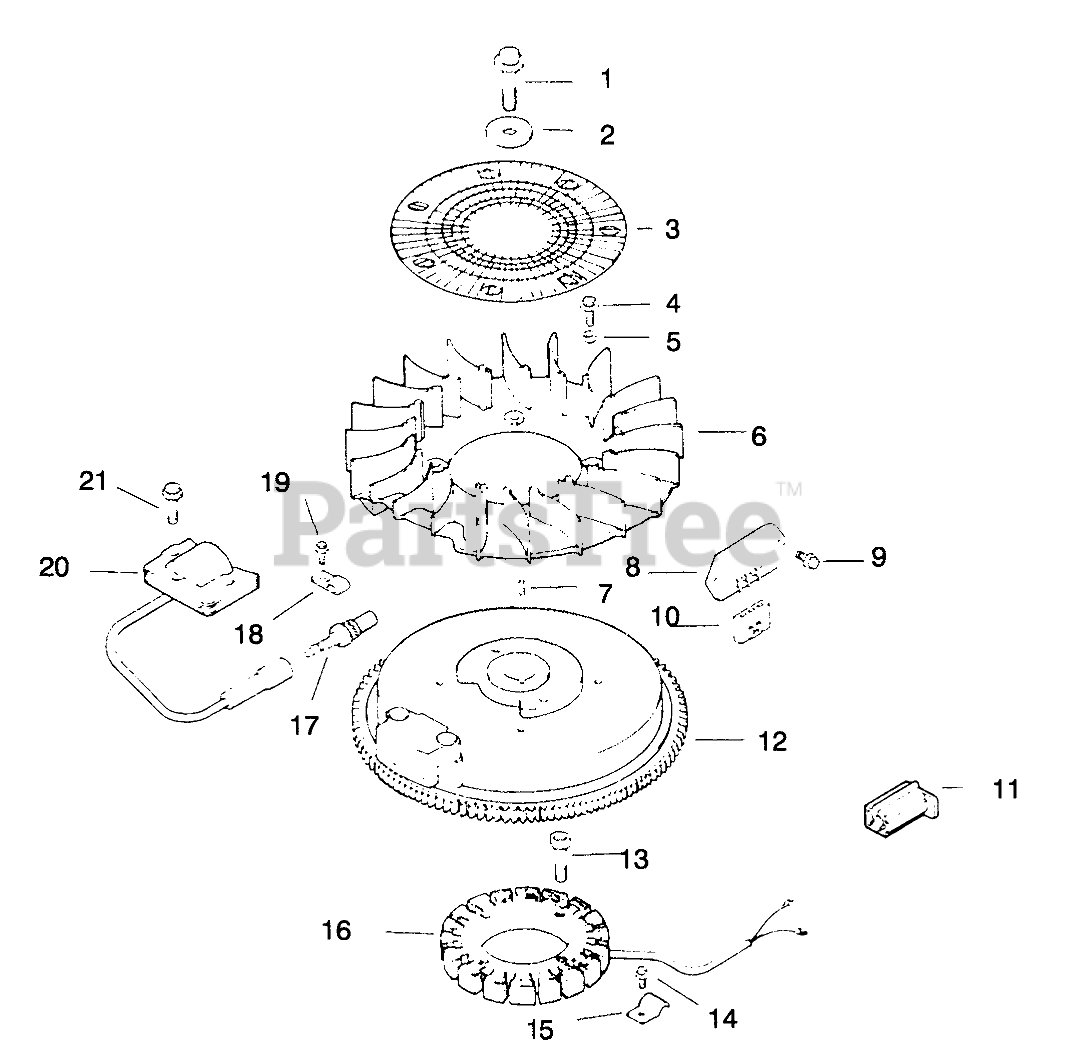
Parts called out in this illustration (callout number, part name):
1	Screw
2	Washer-Flat
3	Screen-Grass
4	Screw
5	Spacer
6	Fan
7	Key
8	Rectifier-Unregulated
9	Screw
10	Connector
11	Connector
12	Flywheel ASM
13	Screw
14	Screw
15	Clip-Stator Harness
16	Stator-15 Amp
17	Plug-Spark
18	Clip
19	Screw
20	Module-Ignition
21	Screw
